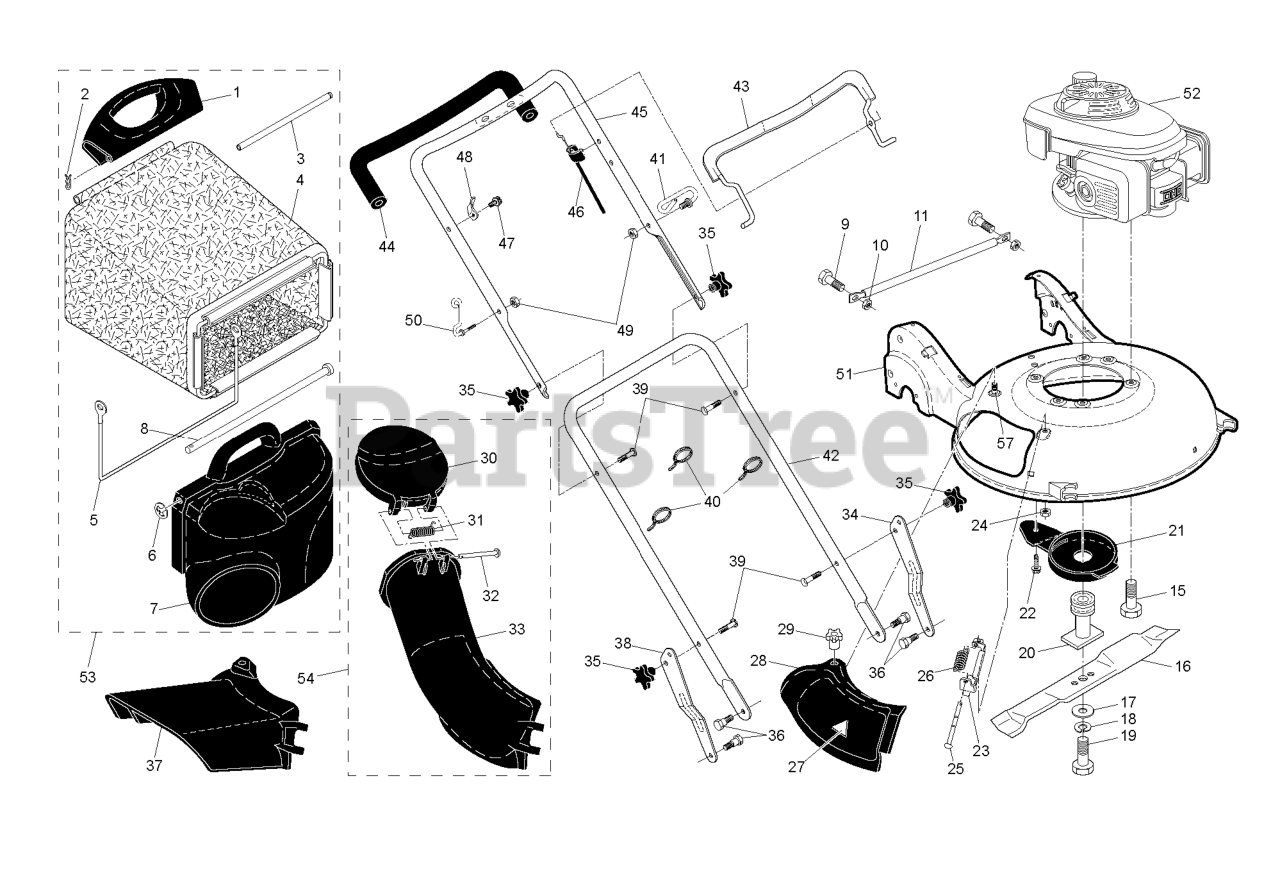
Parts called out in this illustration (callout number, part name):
1	HANDLE.GRASSBAG.REAR.H-GRAY
2	COTTER PIN (3 2)(2 2MC)
3	ROD.REAR.HANDLE.YELLOW
5	FRAME, GRASSBAG
7	DOOR, GRASSBAG
8	ROD, PIVOT
10	LOCKNUT.NYLOC.1/4-20
15	BOLT 3/8-16X1-1/8
16	21" PUSH BLADE
17	WASHER,HARDEN
18	LOCKWASHER
19	BOLT.HD.HEAD.3/8-24X2.50 (2 2)
20	ADAPTER.BLADE
21	DEBRIS SHEILD
22	SCREW 1/4X20
24	LOCK NUT
25	ROD.HINGE.1/4"3.82"
26	SPRING.MULCH.DOOR
27	DECAL.INTERNATIONL.CUTFINGER
28	MULCHER DOOR
29	KNOB.MULCH.DOOR
30	CHUTE.DOOR.21.HV.H-GRAY
32	ROD.HINGE.1/4"3.82"
33	DISCHARGE CHUTE PLASTIC
34	ADJUSTMENT BRACKET, LOWER LH
35	KNOB.HANDLE.STAR.HUSQ.GRAY
36	SHOULDER BOLT
37	GUARD.CLIP.ON.21.HV.GRAY
38	BRACKET.ADJ.LOWER.HDL.RT.GREY
39	BOLT, HANDLE 5/16-18X1.75
40	TIE GUIDE
42	HANDLE.LOWER.GREY
43	BAIL CONTROL
44	GRIP.HANDLE.FOAM.WIDE.(1 SIDE)
45	HANDLE.ASM.UPPER.W/GRIP
46	RB ENGINE ZONE CONTROL CABLE
48	BRACKET
49	NUT
50	GUIDE.ROPE.WALK.MOWER
54	CHUTE.LOWER.ASM.WALK.MOWER
57	STUD.INSERT
58	CLIP.CABLE.BLK
